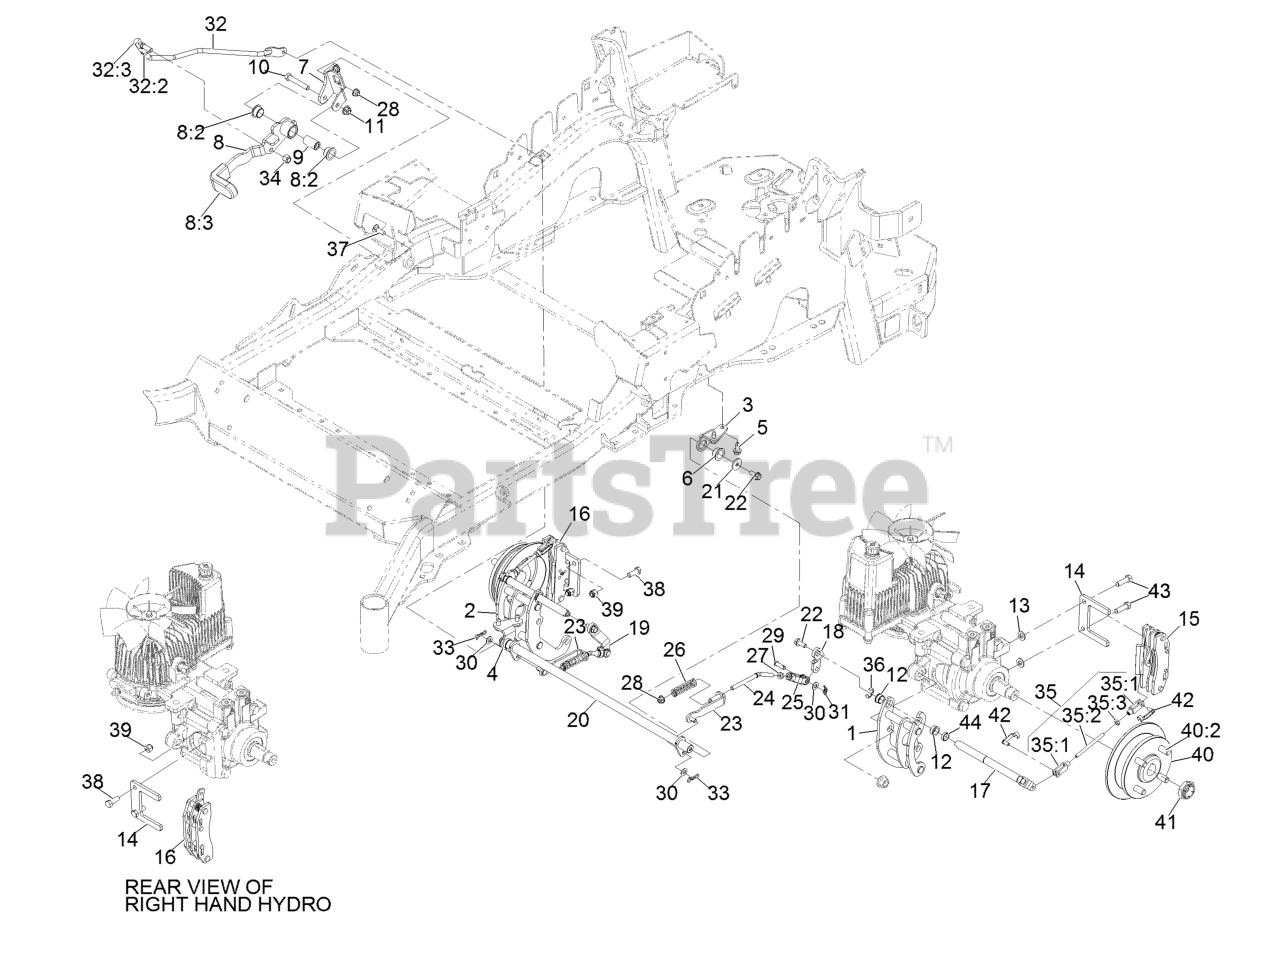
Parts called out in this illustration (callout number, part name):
1	MOUNT-BELLCRANK, LH
2	MOUNT-BELLCRANK, RH
3	MOUNT-PIVOT, LH
4	MOUNT-PIVOT, RH
5	Screw-HWH 5/16-18 X 3/4 Tf
6	BUSHING-FLANGE
7	BRACKET-MOUNT
8	BRAKE LEVER ASM W/ GRIP
8:2	BUSHING-FLANGE
8:3	GRIP-LEVER
9	HANDLE-PIVOT, BRAKE
10	SCREW-HH
11	NUT-HF, NI
12	BUSHING
13	WASHER-FLAT
14	PLATE-MOUNT, BRAKE
15	CALIPER-BRAKE
16	CALIPER-BRAKE, RH
17	BELLCRANK
18	ARM-INNER, LH
19	ARM-INNER, RH
20	SHAFT-CROSS
21	WASHER-FLAT
22	SCREW-HHF
23	BRACKET-L
24	LINKAGE-MID
25	YOKE-OFFSET
26	SPRING-COMPRESSION
27	NUT-JAM
28	NUT-HF, NI
29	PIN-CLEVIS
30	WASHER-PLAIN
31	PIN-COTTER, LOCKING
32	FRONT LINKAGE ASM
32:2	END-TIE ROD, RH
32:3	NUT-HJ
33	PIN-COTTER, LOCKING
34	NUT-LOCK
35	REAR LINKAGE ASM
35:3	NUT-JAM
37	BOLT-CARR
38	SCREW-HH
39	NUT-LOCK, NI
40	WHEEL HUB ASM
40:2	STUD-WHEEL
41	LOCKNUT
42	PIN-CLEVIS, SPRING
43	SCREW-LOCK, PATCH
